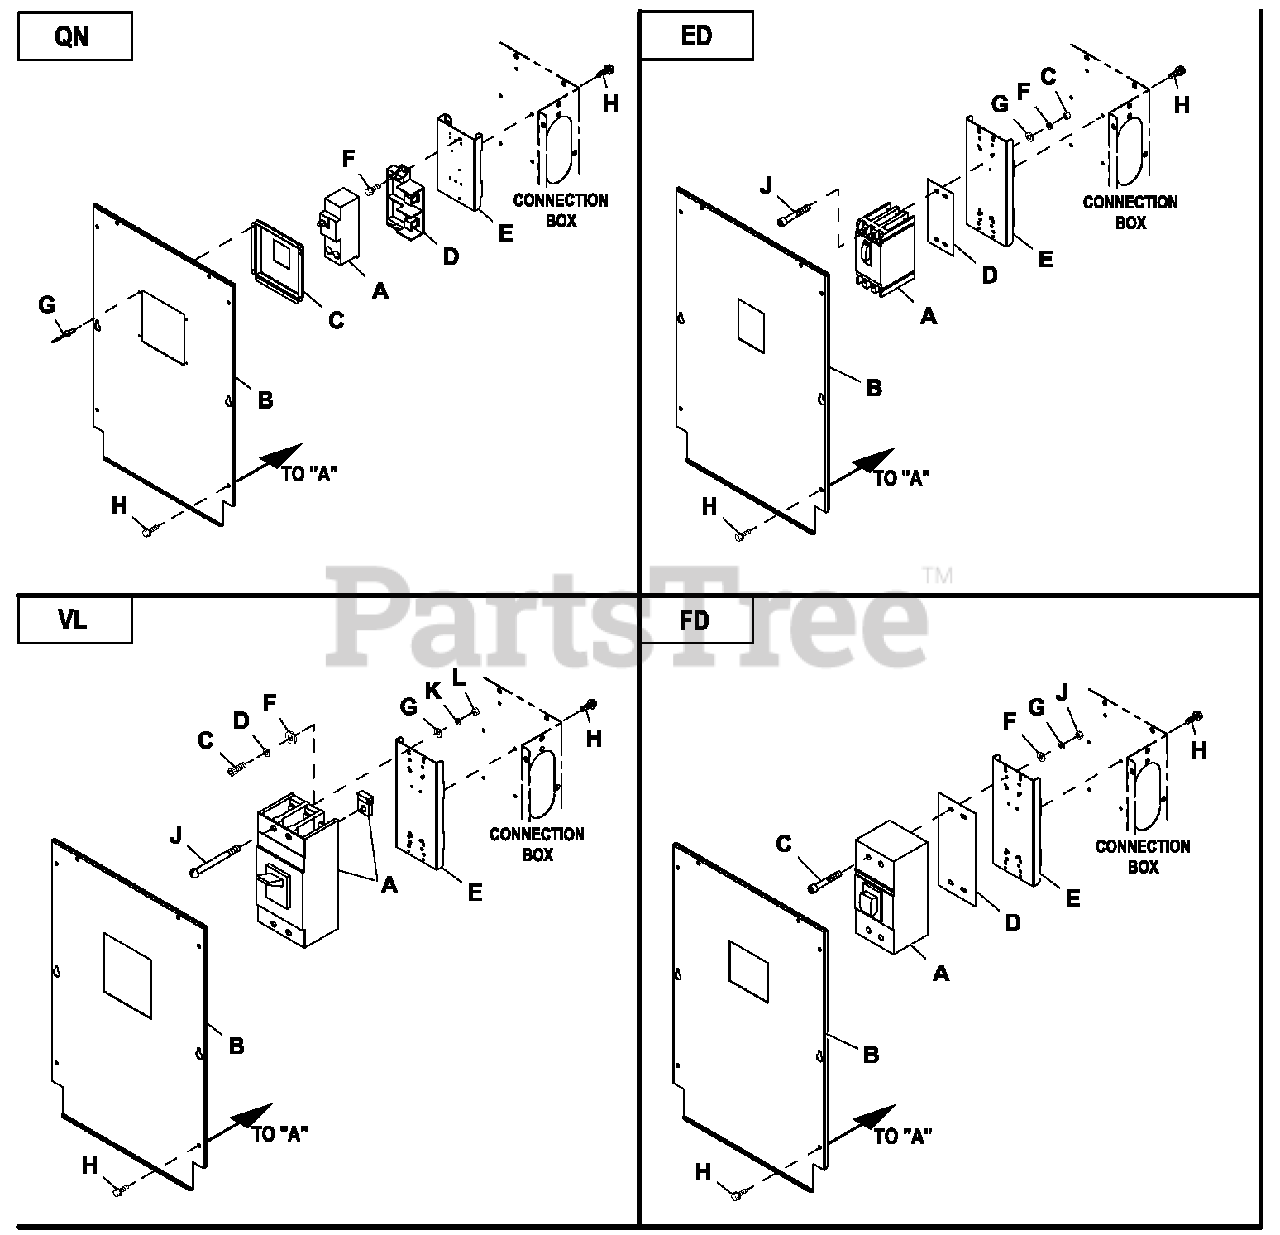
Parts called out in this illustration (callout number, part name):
A	CB 0175A2P 240VS QN2 LL
B	COVER CB C2 CPL
C	COVER CB DISH 2P S QN
D	BASE , QN CIRCUIT BREAKER
E	STANDOFF CB BOX CONBOX
F	SCREW HHTT M5-0.8 X 10 BP
G	RIVET POP .125 X .275 SS
H	SCREW HWHT M6-1 X 16 N WA Z/JS
A	CB 0125A 3P 480V S ED4 LL
B	COVER CB S ED C2 CONBOX
C	NUT HEX #10-32 STEEL
D	INSULATOR CB S(ED-3P)
E	STANDOFF CB MOUNT CONBOX
F	WASHER LOCK#10
G	WASHER FLAT #10 ZINC
J	SCREW RHM #10-32X4-1/2
A	CB 0300A 3P 600V S JG-VL LL
B	COVER CB S JG VL C2 CONBOX
C	SCREW SHC M8-1.25X20 C12.9
D	WASHER LOCK M8-5/16
F	WASHER FLAT 5/16-M8 ZINC
J	SCREW RHM 10-32X4
K	WASHER LOCK#10
L	NUT HEX #10-32 STEEL
A	CB 0150A 3P 600V S FD6 LL
B	COVER CB S FD6 C2 CONBOX
C	SCREW SHC 1/4-20X4.5 G8.8 NZ
D	INSULATOR CB FD FRAME 30MIL
F	WASHER FLAT 1/4-M6 ZINC
G	WASHER LOCK M6-1/4
J	NUT HEX 1/4-20 STEEL
